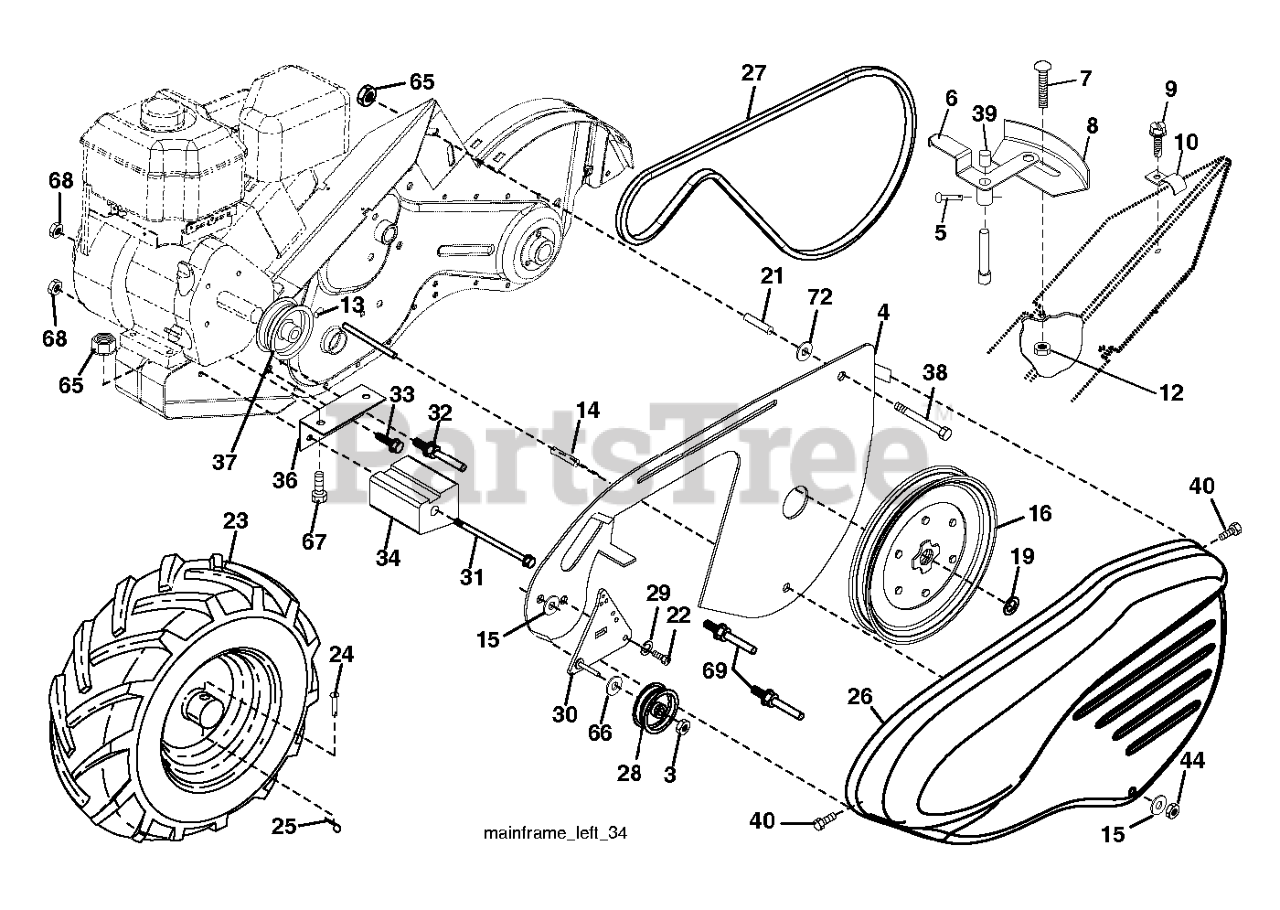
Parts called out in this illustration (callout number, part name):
3	LOCKNUT
4	SHIELD.INNER.BELT.GUARD.RT.BLA
5	PIN.SPIROL.FLARED
6	LEVER.ASM.SHIFT.RED
8	RP.PANEL.SHIFT
9	TAPPING SCREW
10	CONDUIT.CLIP.PLATED
12	NUT
14	SPACER-SPLIT.327 X .42
15	WASHER
16	SHEAVE, TRANSMISSION
19	RETAINING RING LT
21	SPACER SPLIT
23	WHEEL.DRT.LH.13X5X6.SILVER.KEN
24	RIVET,DRILLED
25	RETAINER M
26	GUARD.BELT.TILLER.ORANGE
27	V-BELT
28	PULLEY-IDLER TI
30	BRACKET.IDLER.ASM.LONG
31	BOLT.FIN.HEX.3/8-16UNC
32	SHIFT ARM CRT
33	BOLT
34	COUNTERWEIGHT.LH.CRT
36	BRACKET.REINFORCEMENT.LH.PNT
37	RP.ENGINE PULLEY
38	BOLT
39	CAP.PLUNGER.BLACK
40	SCREW.HEX.WSH.SLT.#10-24X.50
44	NUT.71038.31-18.HEX.NYLOCK
65	LOCKNUT-FLANGE 5/16-18
66	WASHER
67	BOLT, HEX 5/16-18X1-3/4
69	KEEPER.BELT.ENGINE
72	STEEL WASHER
